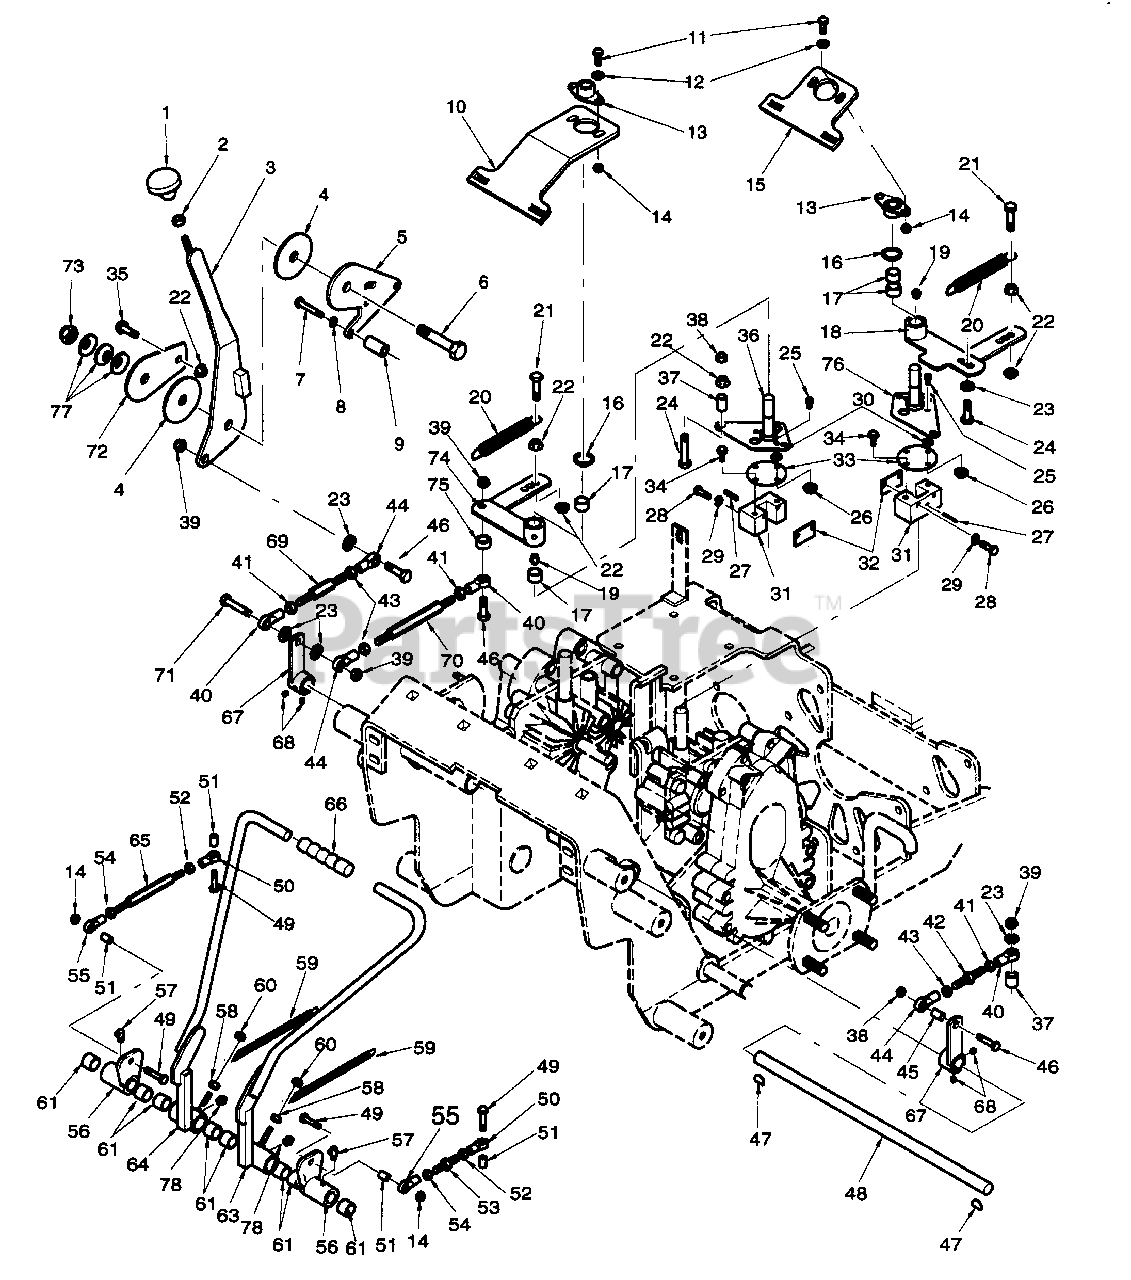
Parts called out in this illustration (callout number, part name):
2	HEX NUT, 3/8-16
3	LEVER, SPEED CONTROL
4	DISC, FRICTION
5	MOUNTING, PLATE, SPEED SELECTOR
6	BOLT, HEX HEAD, 5/8-11 X 2-1/4
7	BOLT, HEX HEAD, 5/16-18 X 2-1/2
8	LOCKWASHER, 5/16
9	SPACER, SPEED CONTROL
10	MOUNTING PLATE, SPEED CONTROL
11	BOLT, HEX HEAD, 5/16-18 X 3/4
12	FLATWASHER, 5/16(.375 X .875 X .083)
13	BUSHING, SELF-ALIGNING
14	HEX LOCKNUT, ELASTIC STOP, 5/16-18
15	MOUNTING PLATE, LEFT BEARING
16	RING, RETAINING, .625
17	BUSHING, OILITE, .627 ID
18	LEVER, L.H. SPEED CONTROL
19	GREASE FITTING
20	SPRING
21	BOLT, HEX HEAD, 3/8-16 X 1-1/4
22	SERR. FL. HEX NUT, 3/8-16
23	FLATWASHER, 3/8(.391 X .938 X .105)
24	BOLT, HEX HEAD, 3/8-16 X 2.0
25	CAPSCREW, SOCKET HEAD, 1/4-20 X 1/2
26	SERR. FL. HEX NUT, 1/4-20
27	ROLL PIN
28	BOLT, HEX HEAD, 1/4-20 X 1-1/4
29	LOCKWASHER, 1/4
30	FLATWASHER, 1/4(.281 X .625 X .065)
31	BLOCK, PUMP CONTROL
32	CLAMP PLATE, PUMP CONTROL
33	PLATE, COUPLER
34	SERR. FL. HEX HEAD CPSCRW, 1/4-20 X 3/4
35	SERR. FL. HEX HEAD CPSCRW, 5/16-18 X 1-1/4
36	ARM, R.H. PUMP CONTROL
37	STOP, PUMP ARM
38	HEX LOCKNUT, 3/8-16
39	HEX LOCKNUT, ELASTIC STOP, 3/8-16
40	BALL JOINT, 3/8-24 R.H. THREAD
41	HEX NUT, 3/8-24 R.H. THREAD
42	LINK
43	HEX NUT, 3/8-24 L.H. THREAD
44	ROD END, 3/8-24 L.H. THREAD
45	SLEEVE
46	BOLT, HEX HEAD, 3/8-16 1-1/2
47	KEY, 3/16 X 5/8 WOODRUFF
48	SHAFT SPEED CONTROL
49	BOLT, HEX HEAD, 5/16-18 X 1-1/2
50	ROD END, 5/16-24 R.H. THREAD
51	SPACER
52	HEX NUT, 5/16-24 R.H. THREAD
53	LINK, SPEED CONTROL
54	HEX NUT, 5/16-24 L.H. THREAD
55	ROD END, 5/16-24 L.H. THREAD
56	CONTROL LEVER
57	GREASE FITTING, 90DEG
58	HEX NUT, 5/16-18
59	SPRING, HANDLE RETURN
60	HEX LOCKNUT, 5/16-18
61	BUSHING, OILITE, .753 ID
63	LEVER, L.H. CONTROL
64	LEVER, R.H. CONTROL
65	LINK, R.H. ADJUSTMENT
66	GRIP, HAND CONTROL
67	LEVER, SPEED CONTROL
68	SETSCREW, SOCKET HEAD, 1/4-20 X 1/4
69	LINK, SPEED CONTROL
70	LINK
71	BOLT, HEX HEAD, 3/8-16 X 1-3/4
72	PLATE, SPEED SELECTOR
73	HEX LOCKNUT, ELASTIC STOP 5/8-11
74	LEVER, R.H. SPEED CONTROL
75	SPACER
76	ARM, L.H. PUMP CONTROL
77	WASHER, BELLEVILLE, 5/8
78	GREASE FITTING
